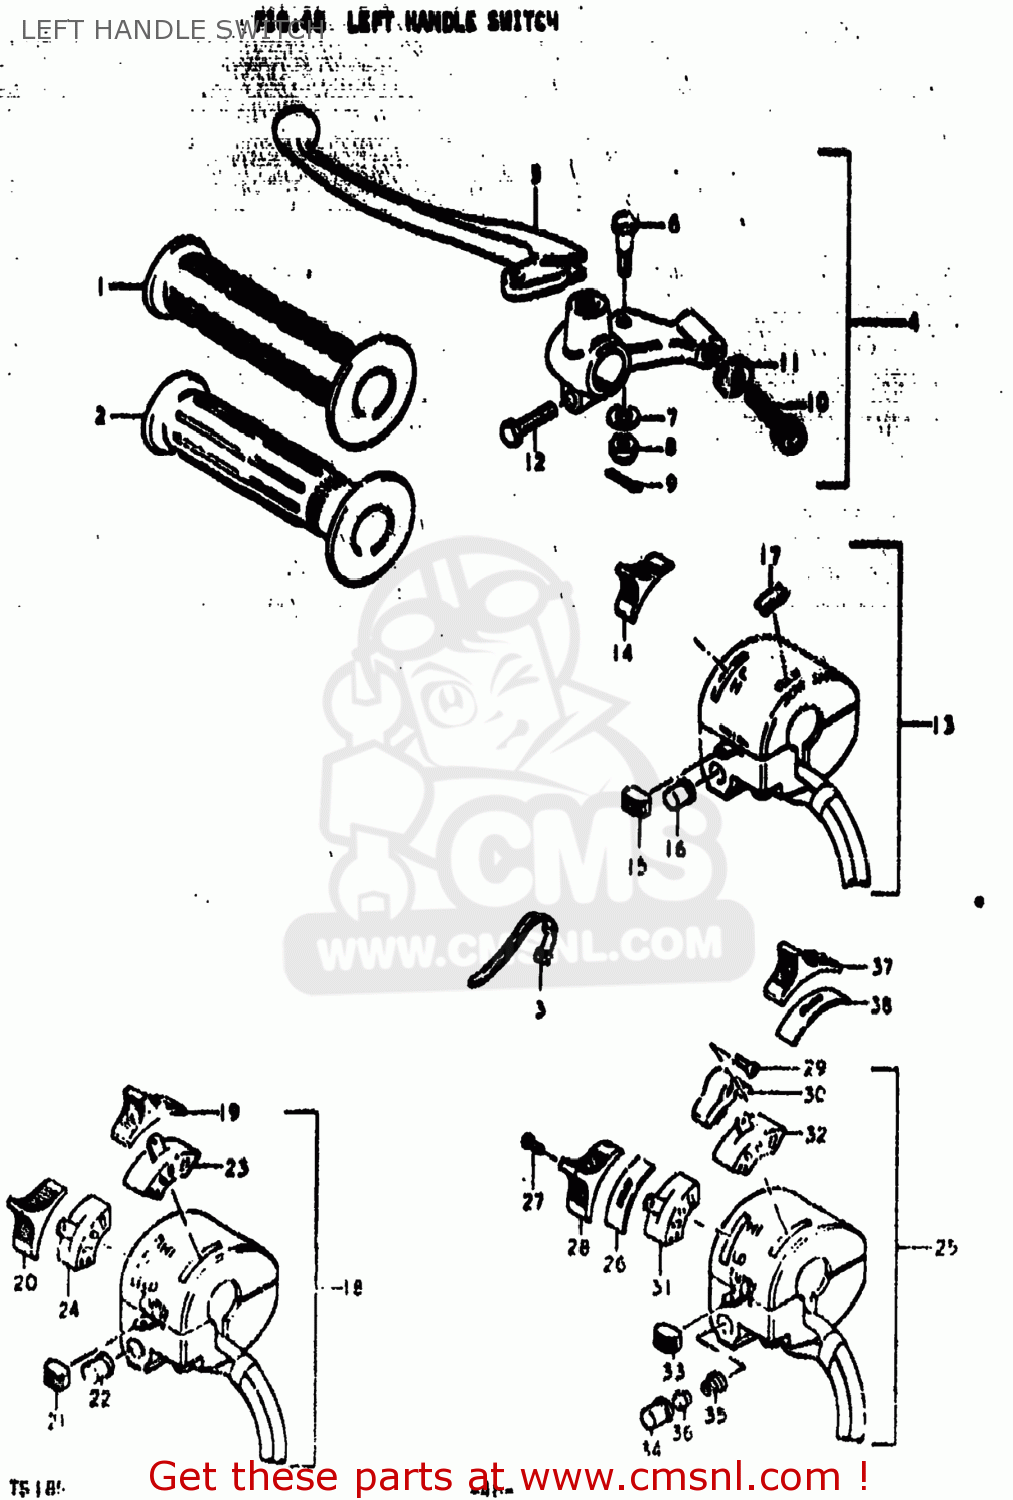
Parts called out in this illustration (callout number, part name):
1	GRIP
2	GRIP,L
3	CLAMP(L:120)
4	LEVER ASSEMBLY
5	LEVER,CLUTCH
6	BOLT,LEVER
7	LOCK WASHER
8	NUT,LEVER FITTNG
9	COTTER PIN
10	ADJUSTER,CABLE
11	NUT,CABLE ADJUSTER
12	BOLT
13	SWITCH ASSEMBLY,HANDLE
14	KNOB,HANDLE SWITCH
15	KNOB,HANDLE SWITCH
16	BUTTON, HORN
18	SWITCH ASSEMBLY,HANDLE
19	KNOB,HANDLE SWITCH
20	KNOB,HANDLE SWITCH,UPPER
21	KNOB,HANDLE SWITCH
22	BUTTON, HORN L,M
24	SLIDING BLOCK, DIMMER SWITCH
25	SWITCH ASSEMBLY,HANDLE,LEFT
26	PLATE,DIMMER KNOB
27	SCREW, DIMMER
28	KNOB,HANDLE SWITCH,UPPER
29	SCREW
30	KNOB
31	SLIDING BLOCK, DIMMER SWITCH
33	KNOB,HANDLE SWITCH
34	BUTTON, HORN
35	SPRING,BUTTON
36	PLATE,HORN BUTTON
37	KNOB,HANDLE SWITCH
38	PLATE,LIGHTING KNOB
